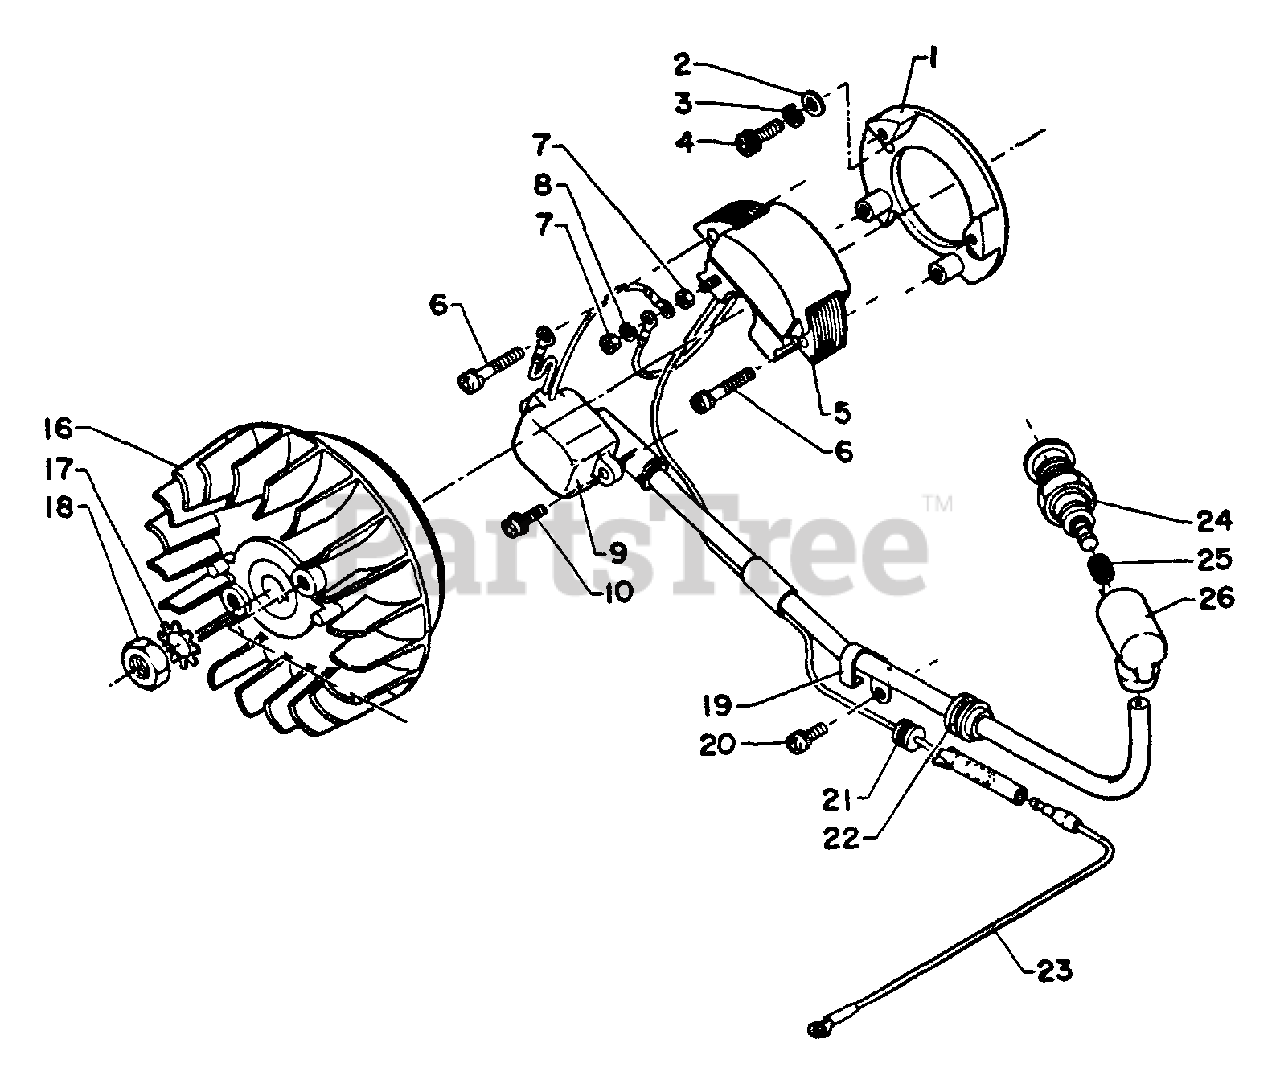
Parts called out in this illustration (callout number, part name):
1	PLATE, STATOR
2	WASHER - 5
3	LOCKWASHER - 5
4	SCREW - 5X15
5	COIL, IGNITION
6	SCREW - 4X25
8	SCREW - 4X25
8	LOCKWASHER - 3
9	COIL, IGNITION
10	SCREW - 4X14
16	FLYWHEEL
17	WASHER - 10
19	CLAMP
20	SCREW - 4X10
21	GROMMET
23	LEAD - GROUND
24	SPARK PLUG -- BPM-7A
25	TERMINAL, SPARK PLUG CAP
26	CAP, SPARK PLUG
